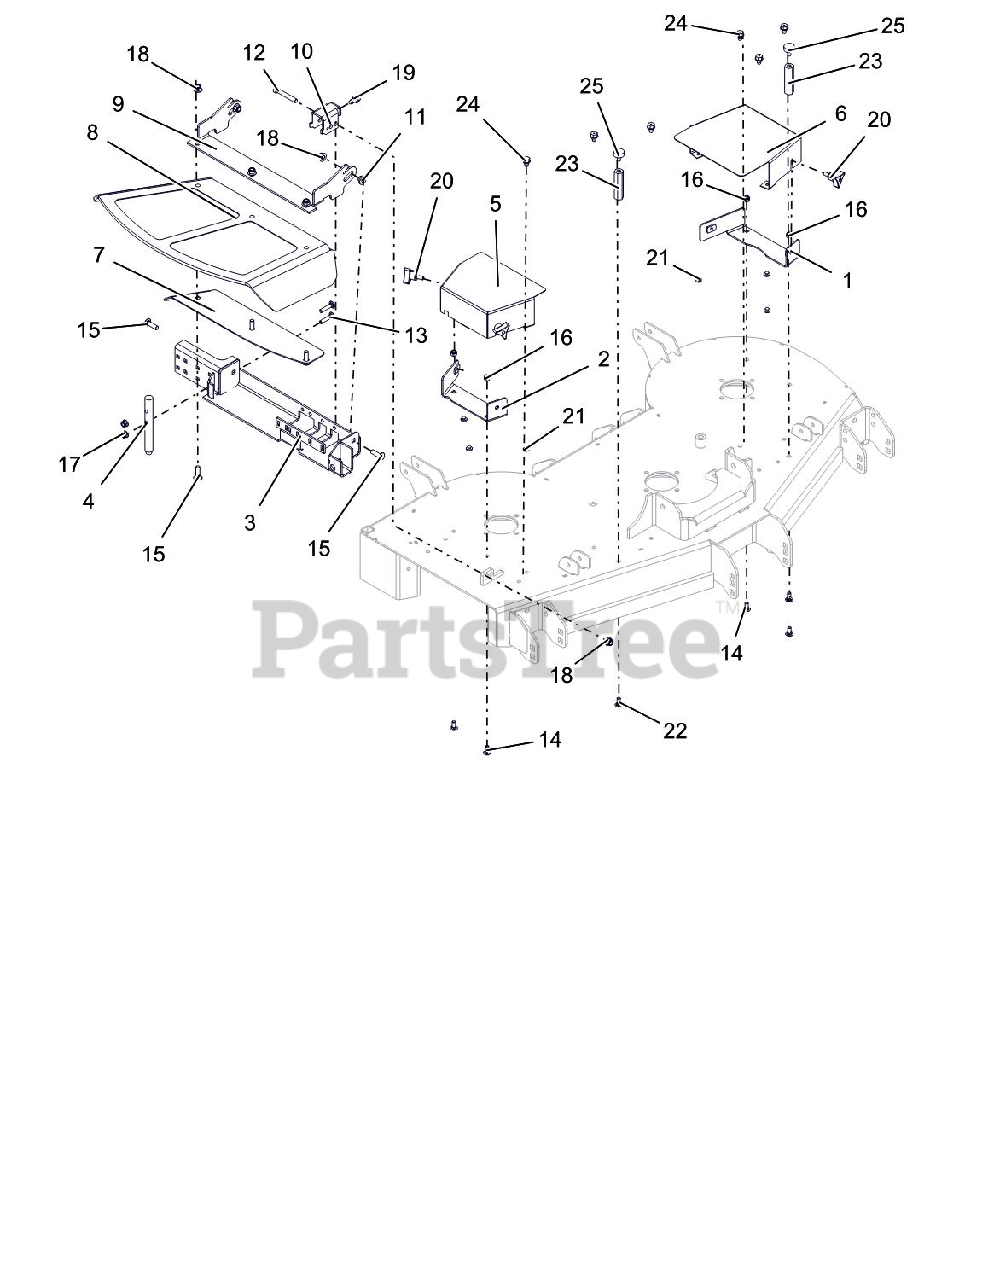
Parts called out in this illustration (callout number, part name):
1	WLDMT, RH BRKT BELT GUARD MOUNTING-RED
2	WLDMT, LH BRKT BELT GUARD MOUNTING-RED
3	WARRANTY CHUTE (RED)
4	PIN, DISCHARGE CHUTE X-DRILLED
5	GUARD, RH DECK BELT
6	GUARD, LH DECK BELT-RED
7	PLATE, 48-60" DISCH CHUTE CLAMP (RED)
8	CHUTE, 48-60" FORMED RUBBER DISCHARGE
9	BRKT, 48-60" CHUTE MTG (RED)
10	BRKT, DISCHARGE CHUTE MTG-RED
11	BSHG, FLG .385 X .500 X .875 X .406
12	BLT-HEX .38-16X2.50 GR5 YWZC
13	BLT-RDHDSQNK .31-18X1.50 G5 YWZC
14	BLT-RDHDSQNK .31-18X.75 G5 YWZC
15	BLT-RHDSSQNK .38-16X1.25 G5YZ
16	NUT-LK-NYL .312-18 YWZC
17	NUT-LK-NYL-FLG .31-18 YWZC
18	NUT-LK-NYL-FLG .38-16 YWZC
19	SCR-TAP .38-16X.75 HWH TR YWZ
20	KNOB, WING STUD .312-18X.75
21	BUMPER GROMMET .125 X .25 REV
22	BLT, RDHDSQNK .31-18X.75 LOCTITE
23	NUT, COUPLING .31-18 X 3.00
24	SCR-TAP .38-16X.50 HWH TR YWZ
25	BUMPER, RUBBER
